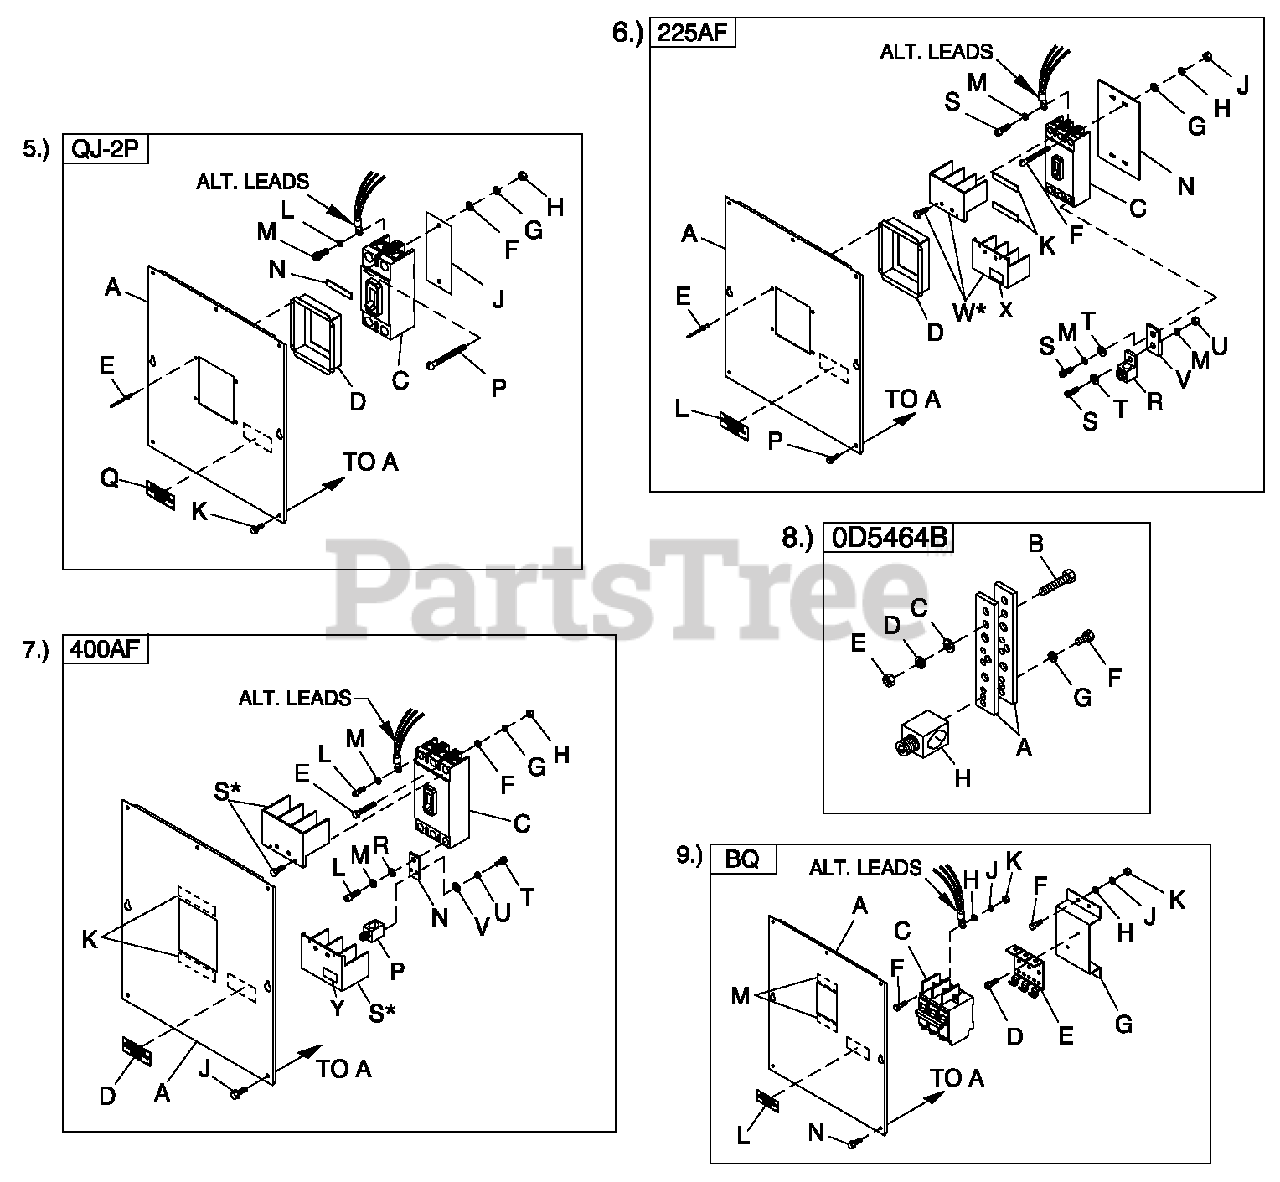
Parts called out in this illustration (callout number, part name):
9	UL CIRCUIT BREAKER (BQ)
A	COVER QJ 2P FRM CB
C	CB 0225A 240V 2P S QJ22
D	COVER QJ 2P CB DISH
E	RIVET POP .125 X .275 SS
F	WASHER FLAT 1/4-M6 ZINC
G	WASHER LOCK M6-1/4
H	NUT HEX 1/4-20 STEEL
J	INSUL CB 2P QJ
K	SCREW THF M6-1 X 16 N WA Z/JS
L	WASHER LOCK 3/8
M	SCREW SHC 3/8-16 X 3/4 G8.8 NZ
N	TAPE ELEC 1/2 FOAM (AS REQ'D)
P	SCREW RHM 1/4-20 X 3
Q	DECAL CUSTOMER CONNECT INSIDE
A	COVER CB C2-C4 225AF
C	CIRCUIT BREAKERS 200A FRAME
D	COVER CB DISH 225AF
F	SCREW RHM #8-32 X 3-1/4
G	WASHER FLAT #8 ZINC
H	WASHER LOCK #8-M4
J	NUT HEX #8-32 STEEL
K	TAPE ELEC 1/2 FOAM
L	DECAL CUSTOMER CONNECT INSIDE
M	WASHER LOCK M8-5/16
N	INSULATOR CB 225AF
P	SCREW THF M6-1 X 16 N WA Z/JS
R	LUG SLDLSS 300 MCM-6 AL/CU
S	SCREW SHC M8-1.25 X 20 G8
T	WASHER FLAT 5/16-M8 ZINC
U	NUT HEX M8-1.25 G8 CLEAR ZINC
V	BUS BAR 200A LUG ADAPTOR
W	TERMINAL COVER CB
X	DECAL TERMINAL SHOCK HZD BI
A	COVER CB C2-C4 400AF
C	CIRCUIT BREAKERS 400A FRAME
D	DECAL CUSTOMER CONNECT INSIDE
E	SCREW RHM 10-32 X 4
F	WASHER FLAT #10 ZINC
G	WASHER LOCK #10
H	NUT HEX #10-32 STEEL
J	SCREW THF M6-1 X 16 N WA Z/JS
L	SCREW SHC M10-1.5 X 25 G12.9
M	WASHER LOCK M10
N	BUS BAR CB ADAPTER 225-400 A
P	LUG SLDLSS 600/250-1/0 X 1/4-28
S	TERM COVER CB
T	SCREW HHC 1/4-28 X 1/2 G5
U	WASHER LOCK M6-1/4
V	WASHER FLAT 1/4-M6 ZINC
W	SCREW SHC M10-1.5 X 25 G12.9
X	WASHER LOCK M10
Y	DECAL TERMINAL SHOCK HZD BI
A	BUS BAR NEUTRAL BLOCK 390
B	SCREW HHC M8-1.25 X 45 G8.8 FT
C	WASHER FLAT 5/16-M8 ZINC
D	WASHER LOCK M8-5/16
E	NUT HEX M8-1.25 G8 YEL CHR
F	SCREW HHC 1/4-28 X 3/4 G5
G	WASHER LOCK 1/4-M6 SS
H	LUG SLDLSS 600/250-1/0 X 1/4-28
A	COVER BQ CIR BREAKER CPL 3P
C	CB 0125A 2P 240V S BQ2 LL
D	SCREW PHTT M4-0.7 X 10 ZYC
E	BRKT CB MTG BACK
F	SCREW RHM #10-32 X 3/4
G	BRKT BQ CB STANDOFF
H	WASHER FLAT #10 ZINC
J	WASHER LOCK #10
K	NUT HEX #10-32 STEEL
M	TAPE ELEC 1/2 FOAM
N	SCREW THF M6-1 X 16 N WA Z/JS
